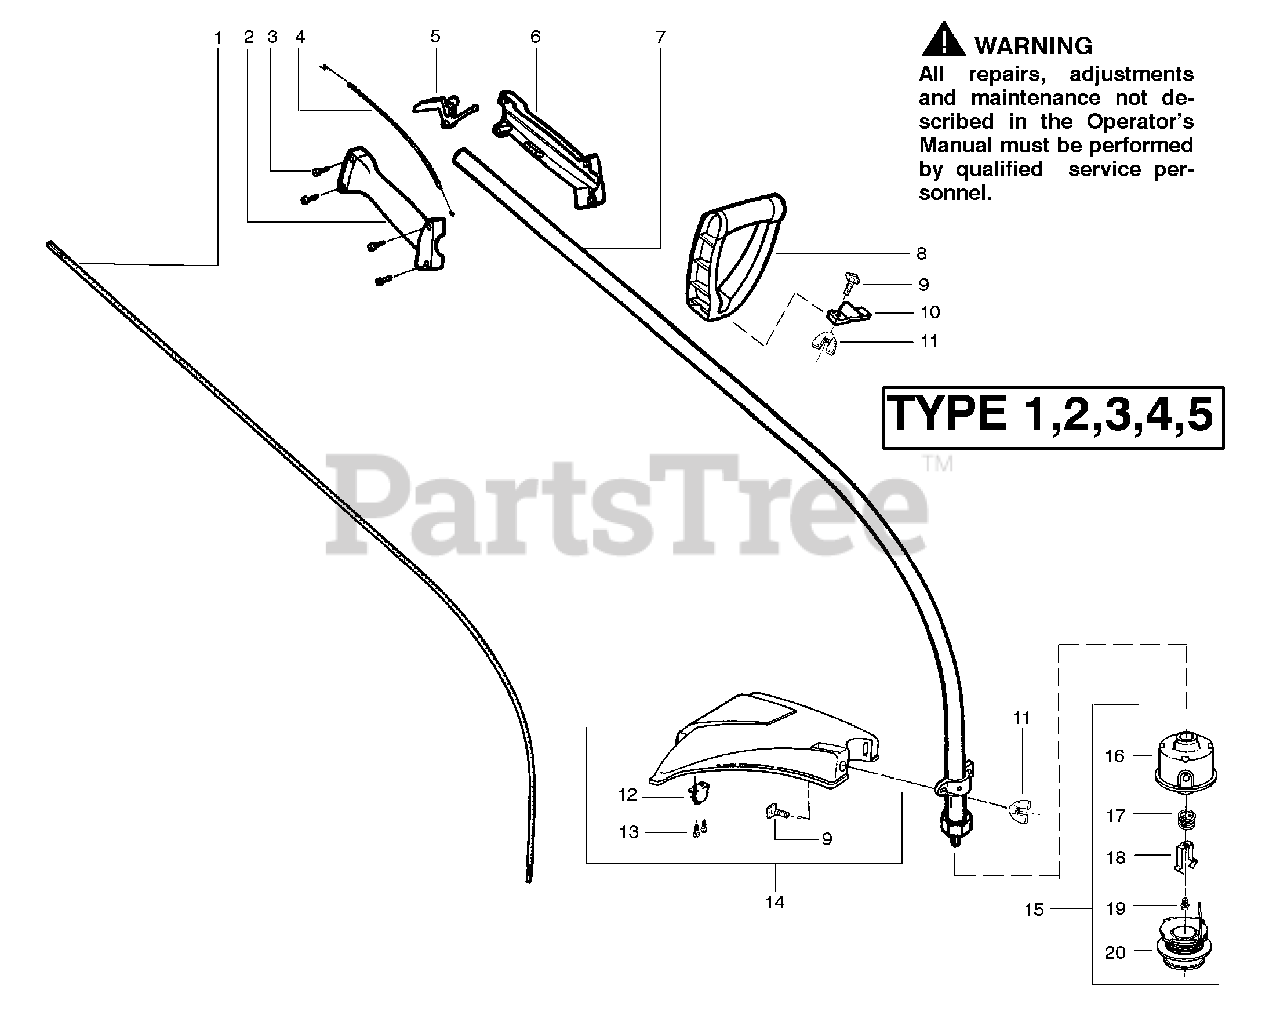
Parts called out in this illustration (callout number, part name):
1	Shaft-Flex
2	Throttle Hsg. (Right)
3	Screw-Throttle Hsg.
4	Kit-Throttle Cable Ass'y.
6	Throttle Hsg. (Left)
7	Drive Shaft Hsg. Ass'y
8	Assist Handle
9	Bolt-Handle/Shield
10	Clamp-Handle Assist
11	Wingnut-Handle/Shield
12	Line Limiter
13	Screw-Line Limiter
14	Kit-Shield Ass'y.
15	Cutting Head Ass'y.
16	Kit-Hub Ass'y
17	Spring-Compression
18	Clip-Retainer-Head
19	Screw w/ Washer-Head
20	Spool w/Line
